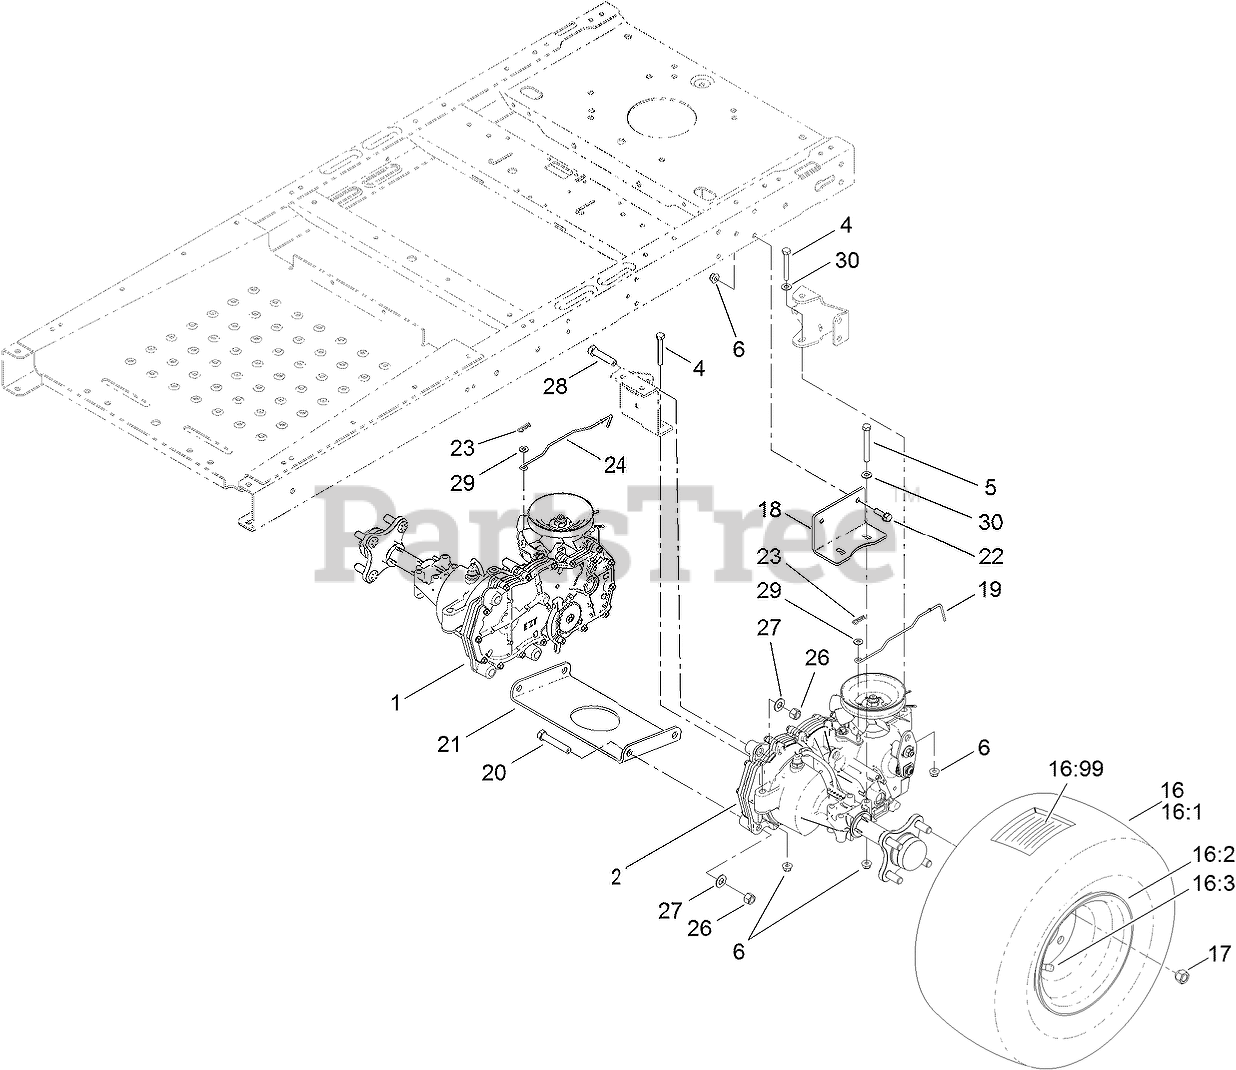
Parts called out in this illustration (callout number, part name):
1	RH HYDRO TRANSAXLE ASM
2	LH HYDRO TRANSAXLE ASM
4	SCREW-HH
5	SCREW-HH
6	NUT-HF, NI
16	4 PLY WHEEL AND TIRE ASM
16:1	TIRE-4 PLY
16:3	STEM-VALVE
16:99	TUBE-TIRE
17	NUT-LUG
18	MOUNT-HYDRO
19	ROD-BYPASS, LH
20	SCREW-HH
21	PLATE-CROSS, HYDRO
22	SCREW-HHF
23	PIN-COTTER
24	ROD-BYPASS, RH
26	NUT-LOCK, NI
27	WASHER-FLAT
28	SCREW-HH
29	WASHER-FLAT
30	WASHER-PLAIN
